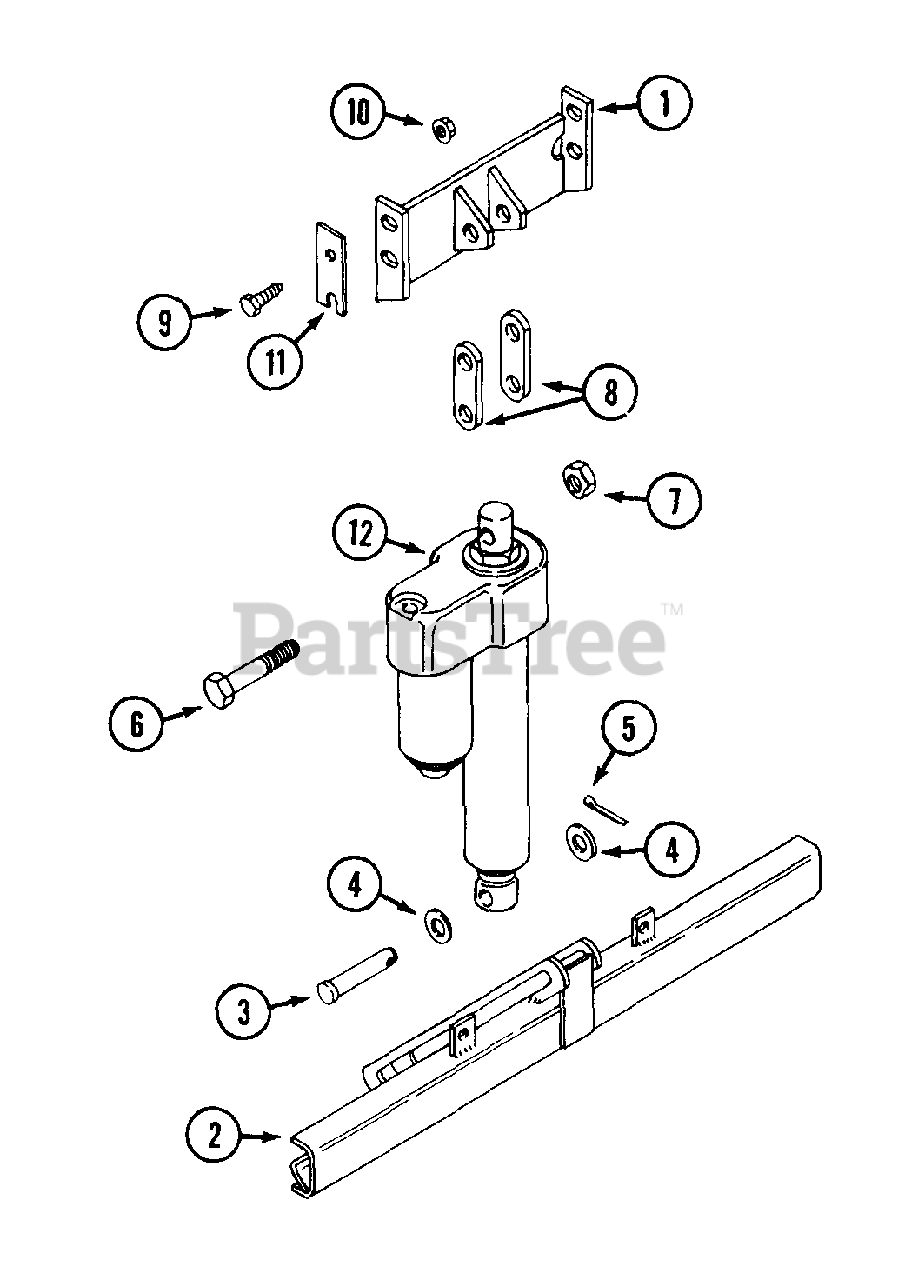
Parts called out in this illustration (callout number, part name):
1	MOUNT - cylinder
3	PIN - clevis 1/2" x 2-1/2"
4	WASHER - 1/2"
5	PIN - cotter 3/32" x 3/4"
6	BOLT - 1/2" - 13 x 2-3/4"
7	NUT - 1/2" - 13 lock
8	LINK - spacer
9	BOLT - 5/16" - 18 x 1"
10	NUT - 5/16" - 18 flange lock
11	SHIM - cylinder mount
12	CYLINDER - lift
